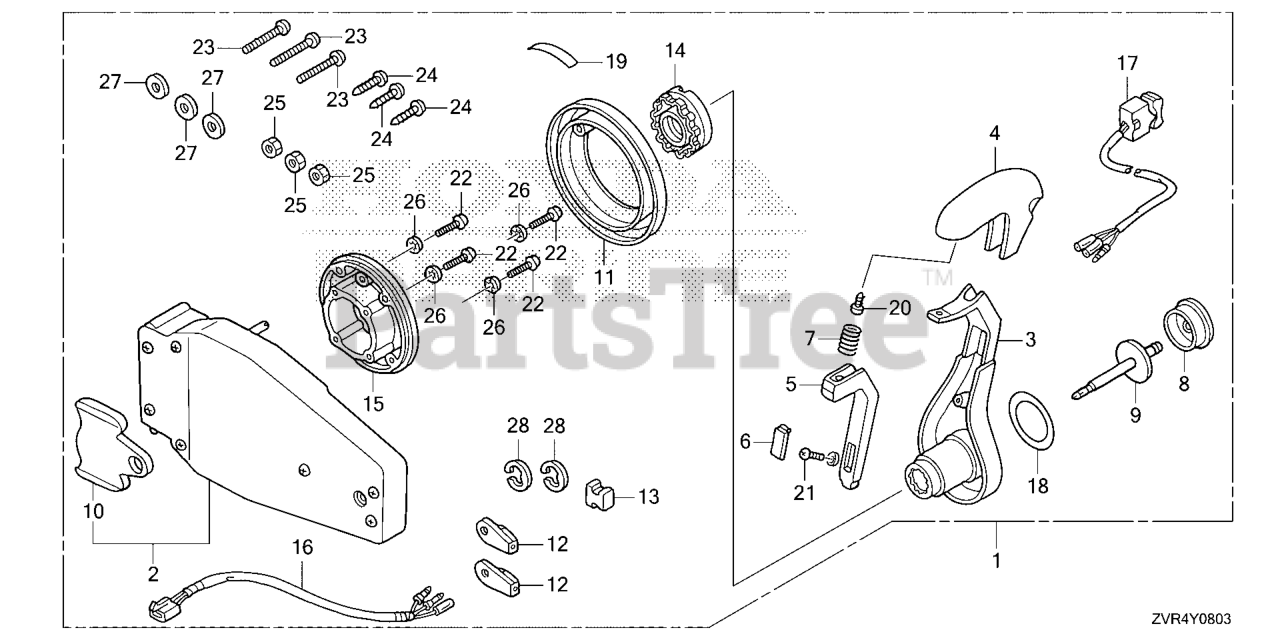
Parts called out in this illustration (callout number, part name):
1	BOX KIT, REMOTE CONTROL (FLUSH MOUNT)(L)
2	HOUSING ASSY., L. (INNER) (FLUSH MOUNT)
3	HANDLE, REMOTE CONTROL
4	COVER, GRIP
5	ARM, NEUTRAL LOCK
6	COVER, LOCK ARM
7	SPRING, NEUTRAL LOCK ARM
8	BUTTON, THROTTLE
9	SHAFT, THROTTLE BUTTON
10	PLATE, DWELL
11	COVER ASSY.
12	TERMINAL, CABLE
13	SPACER, CABLE CLAMP
14	HOLDER, NEUTRAL LOCK
15	BASE
16	SUB-HARNESS ASSY., POWER TRIM-TILT (C)
17	SWITCH ASSY., POWER TRIM-TILT (C)
18	MARK, HANDLE FLUSH MOUNT
19	MARK, FLUSH MOUNT
20	SCREW, PAN (5X16)
21	SCREW, TRUSS (4X12)
22	SCREW, PAN (5X30)
23	SCREW, PAN (6X35)
24	SCREW, TAPPING (6X30)
25	NUT, HEX. (6MM)
26	WASHER, LOCK (5MM)
27	WASHER, PLAIN (6MM)
28	E-RING (6MM)
